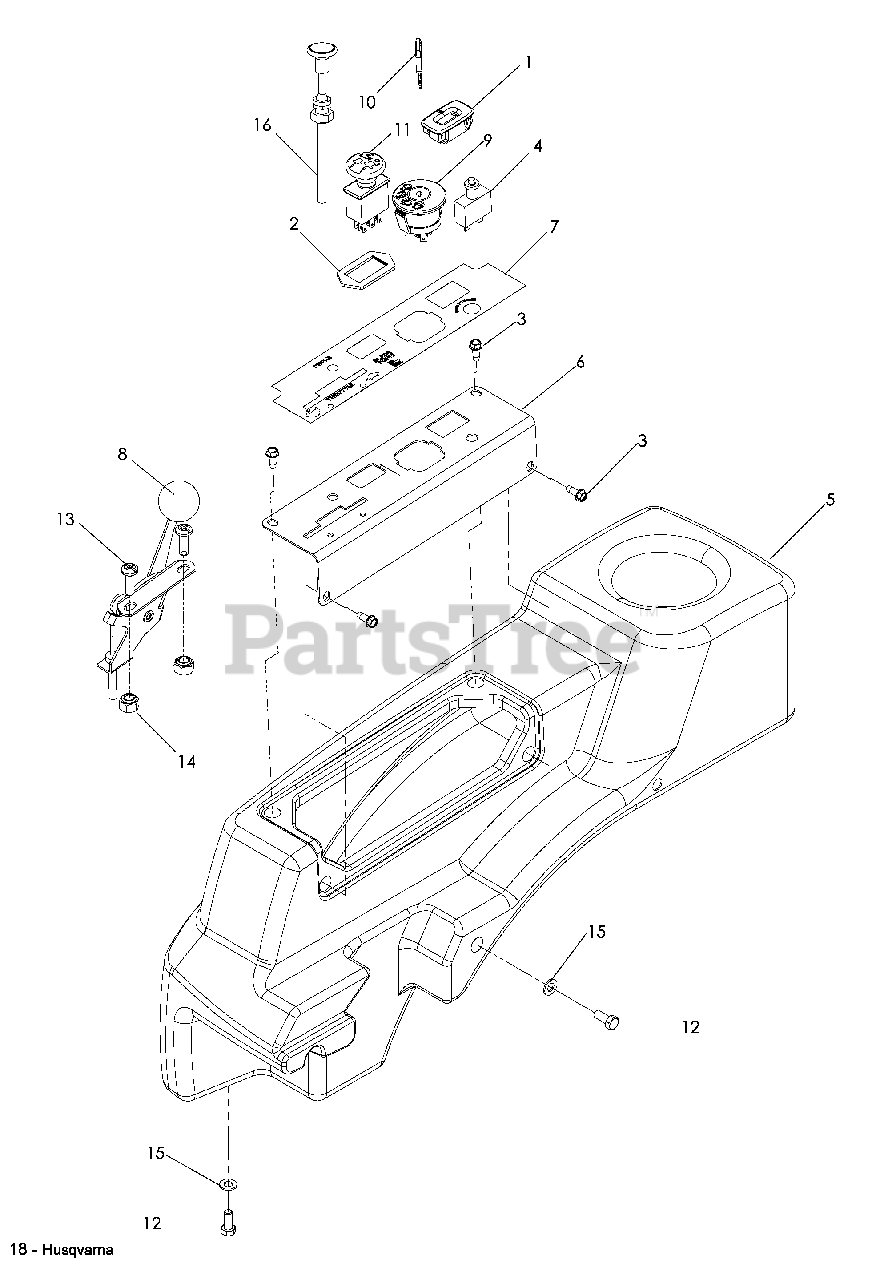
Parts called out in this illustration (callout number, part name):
1	HOUR METER
2	BACKING PLATE
3	SCREW ¼-20 x 5/8, SELF TAP
4	CIRCUIT BREAKER
6	CONTROL PANEL
7	DECAL,CONTROL PANEL
8	THROTTLE CABLE
9	IGNITION SWITCH
10	KEY, IGNITION SWITCH
11	CLUTCH SWITCH
12	HHB 5/16-18 x ¾
13	SCREW #10-24 x 5/8 PAN HD
14	NUT 10-24 NYLOC
15	WASHER 5/16
16	CHOKE CABLE
